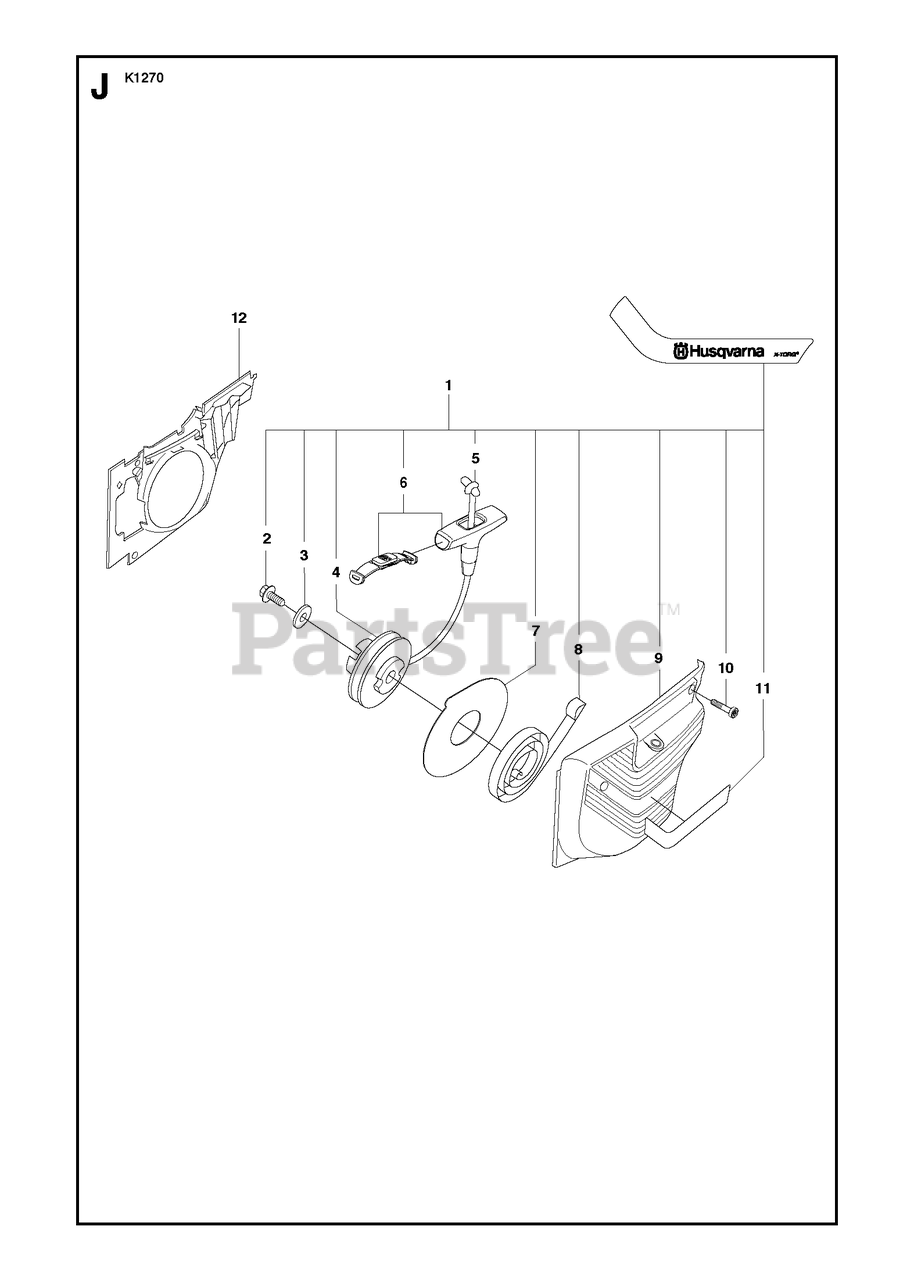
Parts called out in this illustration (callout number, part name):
2	SCREW IHSCT
5	STARTER CORD
5	STARTER CORD50 meter
6	STARTER HANDLE ASSY
7	DAMPING DISC
8	RECOIL SPRING
9	STARTER COVER
10	SCREW ITXSCM
12	AIR CONDUCTOR
12	AIR CONDUCTORRail Stop Switch only
